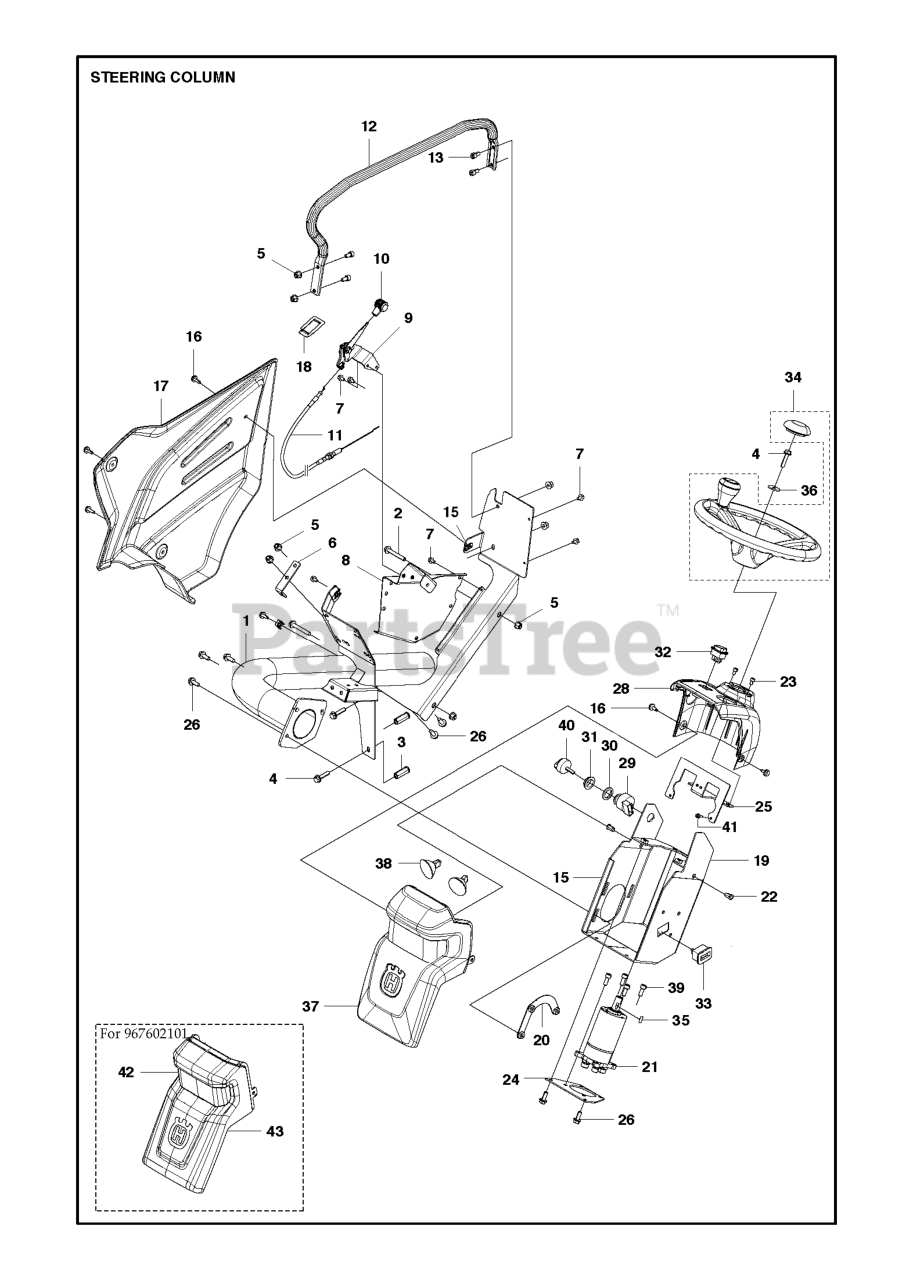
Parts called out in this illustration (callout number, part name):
2	SCREW EHHFM
4	SCREW EHHFM
5	NUT FLANGE
23	SCREW MC6S 6X10
41	SCREW
